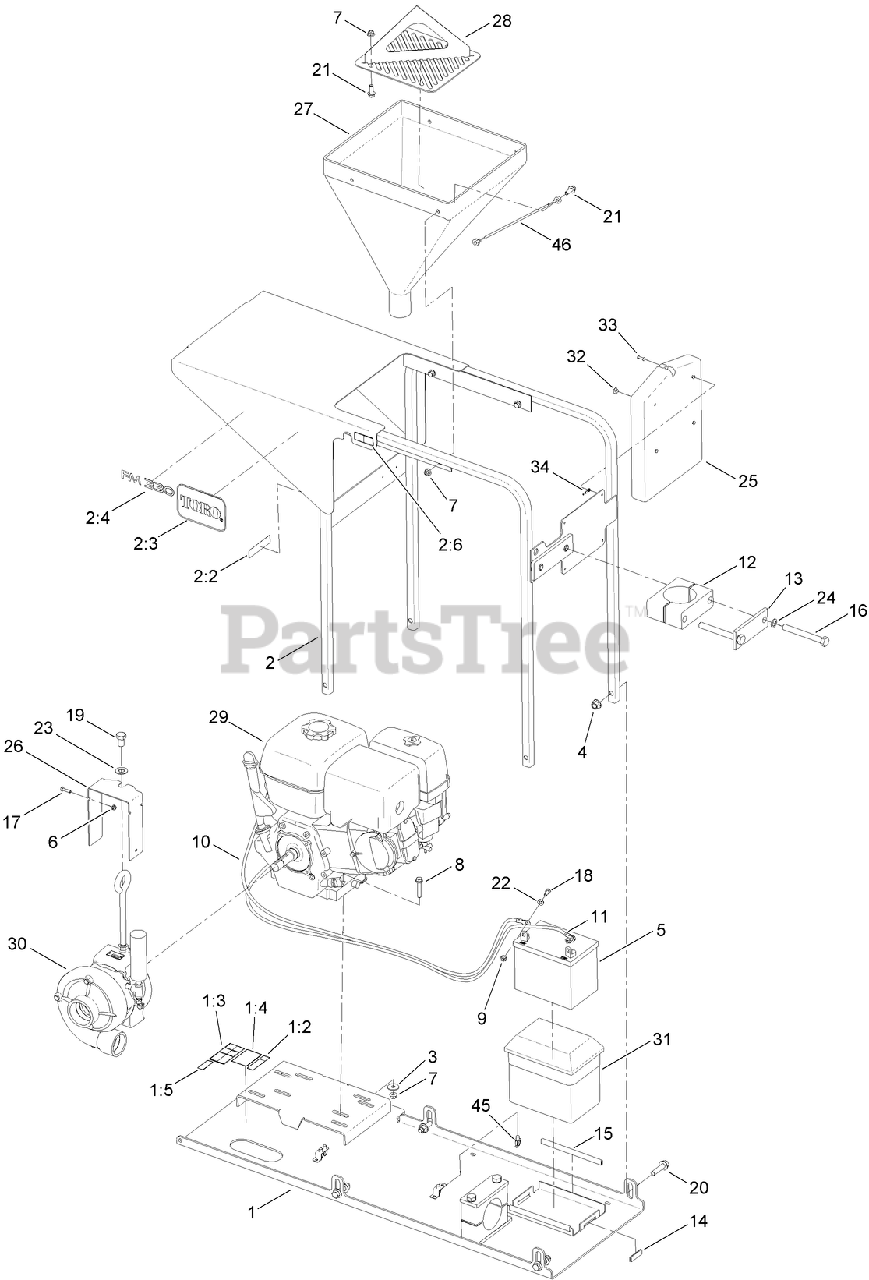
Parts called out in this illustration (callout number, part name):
1	BASE FRAME ASM
1:2	DECAL-DANGER
1:3	DECAL-WARNING, MIXER
1:4	DECAL-DRAIN
1:5	DECAL-FUEL, E10
2	HOPPER SUPPORT ASM
2:2	DECAL-ARRESTER, SPARK
2:3	DECAL
2:6	Decal-Warning, Puncture
3	WASHER-HARDENED
4	NUT-LOCK
5	BATTERY (300 CCA, WET)
6	NUT-HF
7	NUT-HF, NI
8	SCREW-HHF
9	NUT-HHF, SMOOTH
10	CABLE-BATTERY, POSITIVE
11	CABLE-BATTERY, NEGATIVE
12	CLAMP-PIPE
13	PLATE-CLAMP
14	TRIM-STRAP, BATTERY
15	TRIM-TANK
16	SCREW-HH
17	SCREW-HH
18	SCREW-HH
19	SCREW-HH
20	SCREW-HHF
21	SCREW-HHF
22	WASHER-PLAIN
23	WASHER-FLAT
24	WASHER-FLAT
25	HOLDER-MANUAL, OPERATOR
26	GUARD-COUPLER, ROTATING
27	HOPPER-MIX
28	CUTTER-BAG
29	ENGINE-HONDA
30	PUMP ASM
31	BOX-BATTERY
33	POST-MANUAL
34	LANYARD
45	CLIP-TIE
46	LANYARD-GATE
